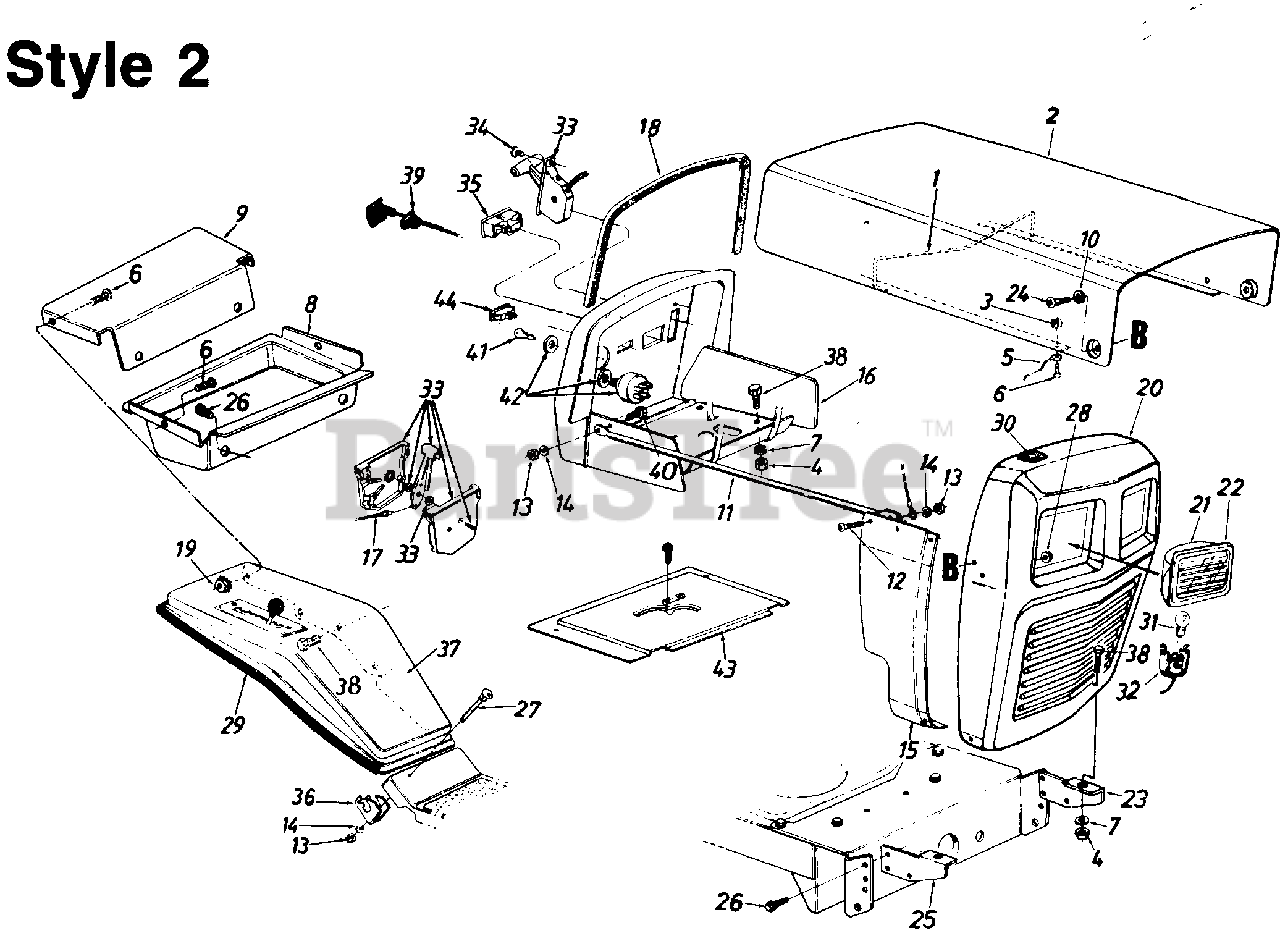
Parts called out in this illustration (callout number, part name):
1	Hood Spring
4	Hex Nut 5/16-18 Thd.
5	Hood Stop 7" Lg.
6	Truss Hd. Scr. #10-24 x 1/2"
7	L-Wash. 5/16" I.D.
8	Tool Tray
11	Grille Support Rod
12	Truss Hd. Scr. 1/4-20 x .75"
13	Hex Nut 1/4-20 Thd.
14	L-Wash. 1/4" I.D.
18	Molding Strip 31" Lg.
19	Hex Sems Nut #10-24 Thd.
22	Headlight Lens
25	Mounting Brkt.
26	Hex Wash. Hd. AB-Tap Scr. 5/16 x .75" Lg.
27	Carriage Bolt 1/4-20 x 2.0" Lg.
28	L-Nut 1/4-28 Thd.
29	Trim Strip-57" Lg.
30	Foam Strip 3/8 x 1-1/8 x 11/2
31	Bulb
32	Twist Lock Lamp Socket
33	Throttle Box Ass'y.
34	Truss Mach. AB-Tap Scr. #10 x .5" Lg.
35	Ammeter
36	Fender Clamp
37	Fender
39	Choke Control 29" Lg.
40	Hex Bolt 1/4-20 x .62" Lg.
41	Ignition Key
42	Ignition Switch
43	Shift Cover
44	Light Switch
